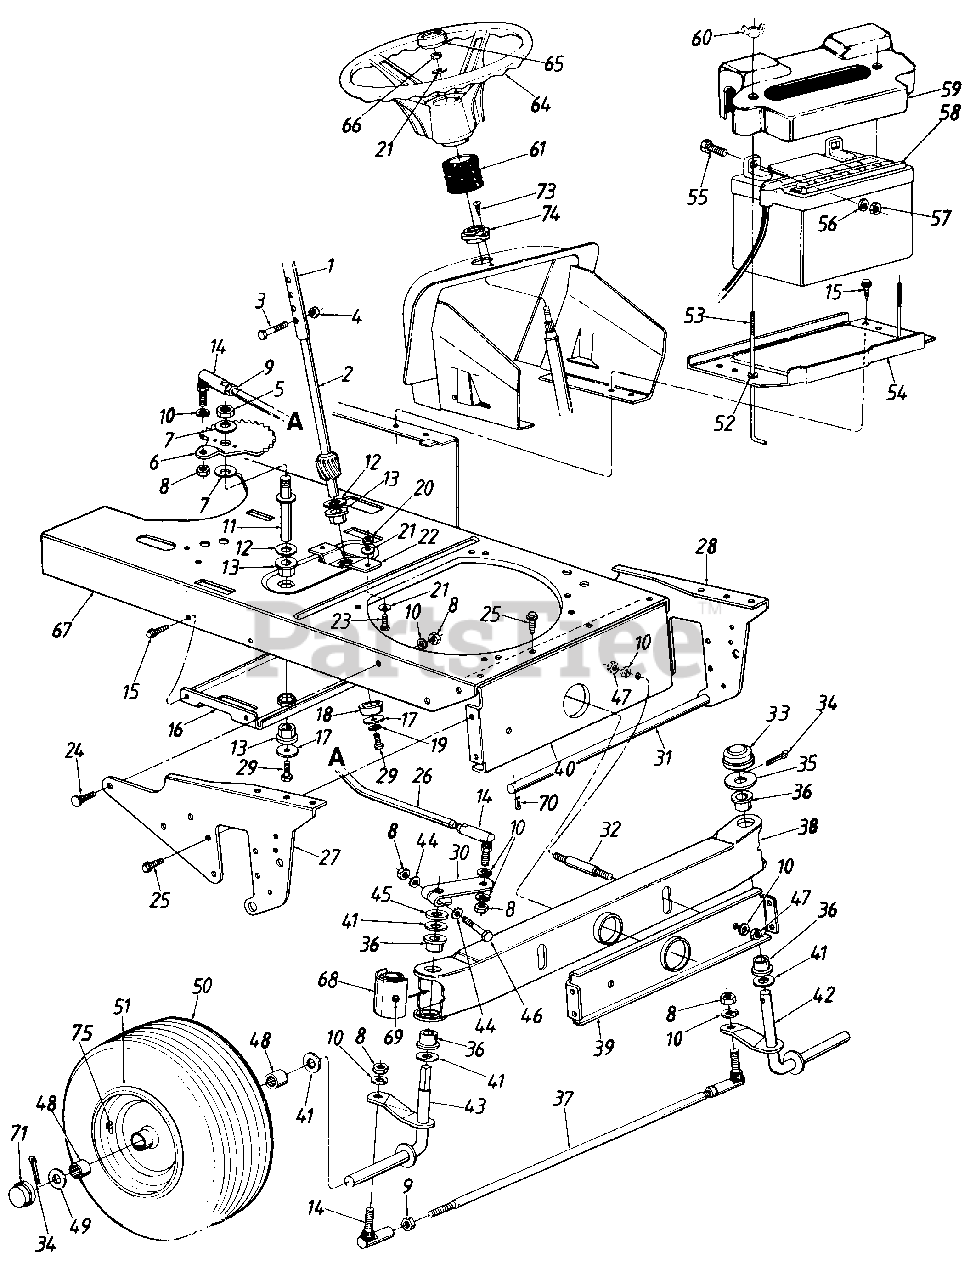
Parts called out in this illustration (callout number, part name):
1	Steering Column Ass'y.
2	Lower Steering Shaft
3	Hex Bolt 1/4-20 x 1.31" Lg.
4	Hex L-Nut 1/4-20 Thd.
5	Hex Nut 5/8-18 Thd.
6	Steering Gear Segment
7	Bell-Wash. 5/8" I.D. x 1.25" O.D.
8	Hex Nut 3/8-24 Thd.
9	Hex Jam Nut 3/8-24 Thd.
10	L-Wash. 3/8" I.D.
11	Steering Gear Segment Shaft
12	Fl-Wash. .64" I.D. x 1.24" O.D.
13	Hex Flange Brg. .63" I.D.
14	Ball Joint Ass'y.
15	Hex Wash. Hd. TT-Tap Scr. 1/4-20 x .5" Lg.
16	Deck Idler Support Brkt.
17	Fl-Wash. .33" I.D. x 1.25" O.D.
18	Spacer .985" I.D. x 1.25" O.D.
19	L-Wash. 5/16" I.D.
20	Hex Nut 5/16-24 Thd.
21	Bell-Wash. .345" I.D. x .88" O.D
24	Ribbed Neck Bolt 3/8-24 x .8"
25	Hex Wash. TT-Tap Scr. 5/16-18 x .62" Lg.
26	Steering Drag Link
27	Pivot Bar Side Plate R.H.
28	Pivot Bar Side Plate L.H.
29	Hex Bolt 5/16-18 x .62" Lg.
30	Steering Arm
31	Deck Connecting Rod
32	Pivot Bar Shld. Bolt 3/8-16 x 5/8" Lg.
33	Cap
34	Cotter Pin 5/32" Dia.
35	Flat Washer
36	Flange Brg. .757" I.D.
37	Tie Rod 20.25" Lg.
38	Pivot Bar Assy.
41	Fl-Wash. .76" I.D. x 1.49" O.D.
42	Front Axle Ass'y. L.H.
43	Front Axle Ass'y. R.H.
44	Bowed Washer
45	Spacer .755" I.D. x 1.25" O.D.
46	Hex Bolt 3/8-24 x 2.25" Lg.
47	Hex Nut 3/8-16 Thd.
48	Needle Brg. .75" I.D.
49	Fl-Wash. .71" I.D. x 1.5" O.D.
50	Wheel Ass'y. Comp.
51	Rim Only
52	Push Nut
53	Battery Hold Down Rod
54	Battery Carrier
55	Hex Bolt 1/4-20 x .62" Lg.
56	L-Wash. 1/4" I.D.
57	Hex Nut 1/4-20 Thd.
58	Battery
59	Battery Cover
60	Wing Nut Plastic 1/4-20 Thd.
61	Steering Bellow
64	Steering Wheel
65	Steering Wheel Cap
66	Hex L-Nut 5/16-24 Thd.
67	Lower Frame
68	Pivot Bar End Cap
69	Grease Fitting
70	Internal Cotter Pin
71	Hub Cap
73	Oval Hd. Cr.-Sunk Scr. #10 x 518" Lg.
74	Fl-Bearing .89" I.D. x 1.36" O.D.
75	Air Valve
